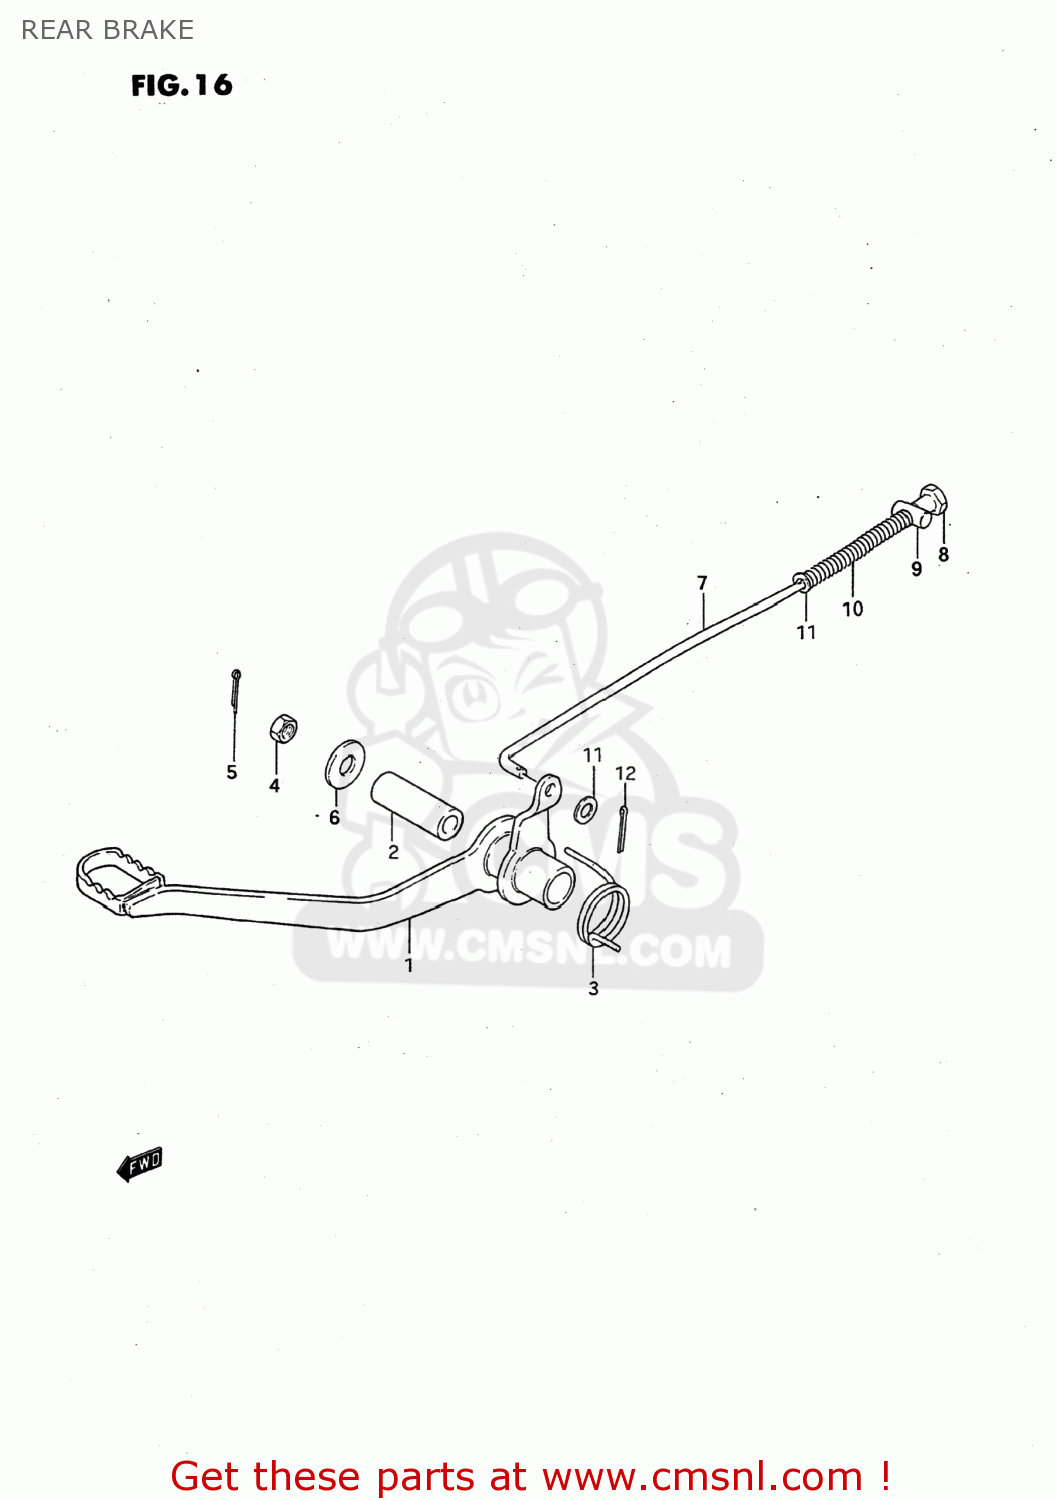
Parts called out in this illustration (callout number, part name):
1	PEDAL,BRAKE
2	SPACER,BRAKE PEDAL
3	SPRING,BRAKE PEDAL RETURN
4	NUT
5	PIN 25X20
6	WASHER
7	ROD ASSY,RR BRAKE
8	NUT
9	PIN,10X19
10	SPRING
11	WASHER
12	PIN
